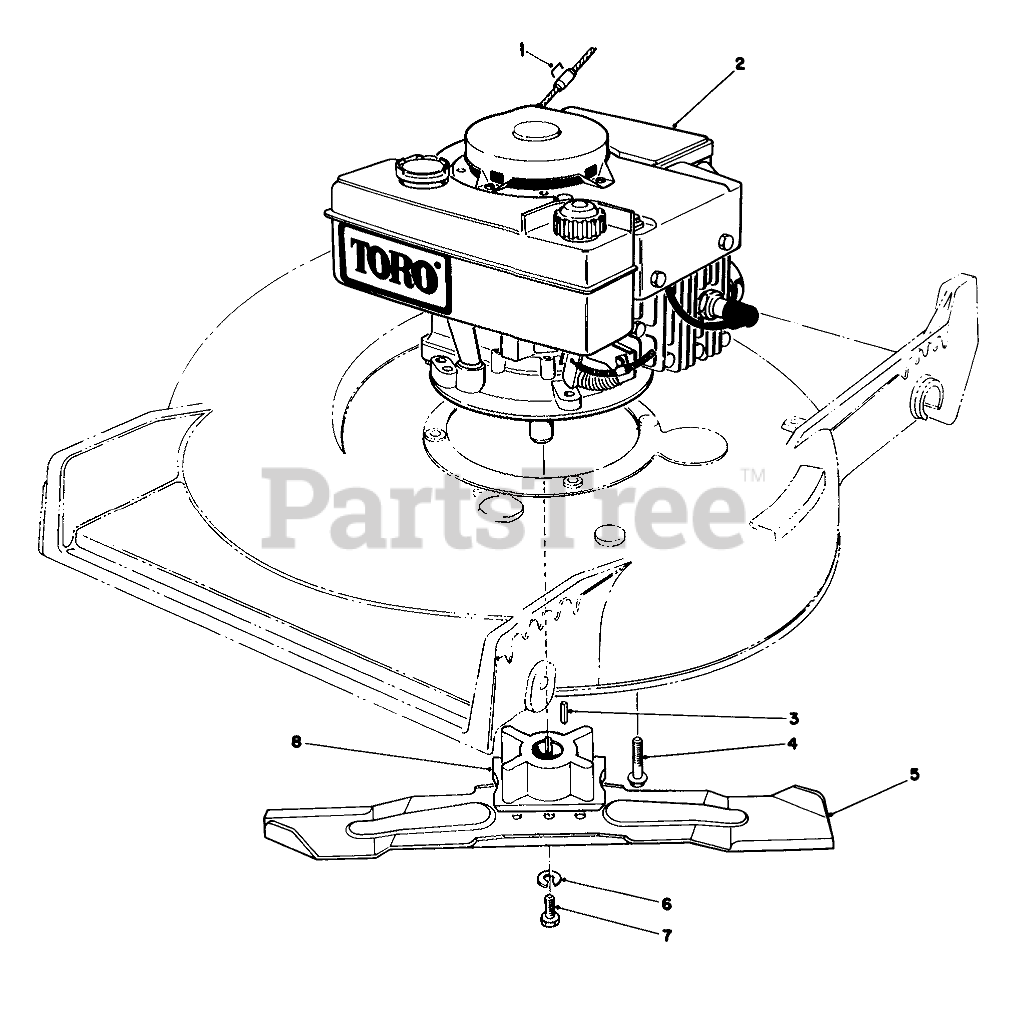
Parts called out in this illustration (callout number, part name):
1	Staple
3	KEY-SQUARE
4	3/8-16 X 2 CAPSCREW
5	BLADE-21in
6	WASHER-LOCK
7	SCREW-BLADE
8	BLADE RETAINER(DEEP)
8	Retainer Blade
